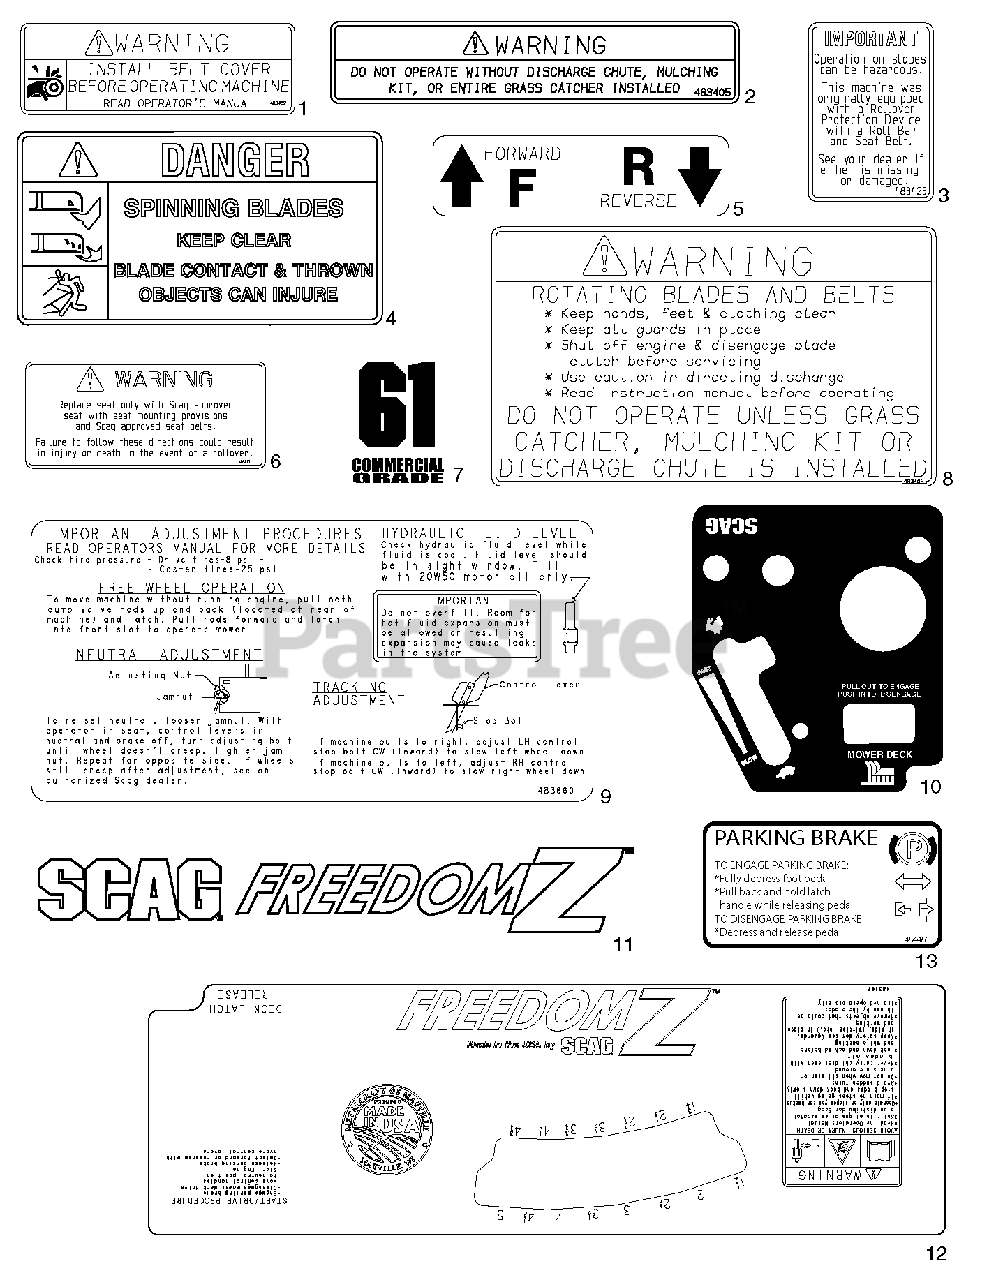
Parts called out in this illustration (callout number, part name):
1	Decal, Belt Cover
2	Decal, Warning
3	Decal, ROPS
4	Decal, Spinning Blades
5	Decal, Traction Control
6	Decal, Seat Replacement
7	Decal, 52 Commercial
7	Decal, 61 Commercial
8	Decal, Knives
9	Decal, Adjustment SFZ
10	Decal, Instrument Panel
11	Decal, Front SFZ
12	Decal, Cutting Height - SFZ61
13	Decal, Brake
